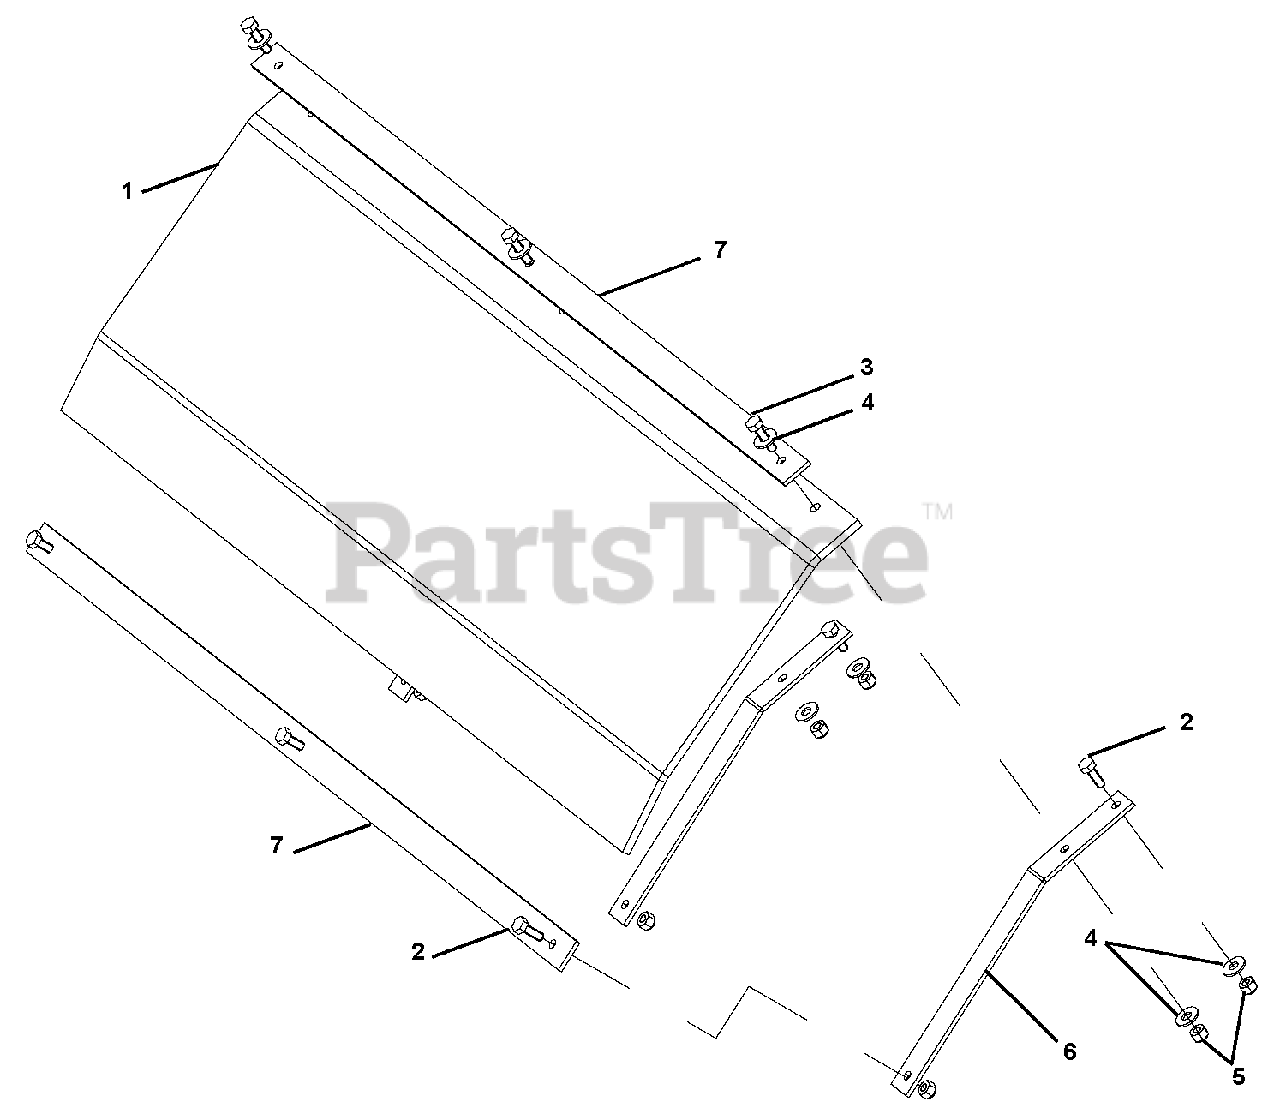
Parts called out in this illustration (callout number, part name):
1	Deflector, 3’ MCD
2	Bolt-Hex .25-20 x 1.25 Grade 5
3	Bolt-Hex .25-20 x 1.50 Grade 5
4	Washer-Flat-Steel .312 x .734 x .065
5	Nut-Locking-Nylon .2500-20
6	Strap, Deflector Support
7	Strap, Support
